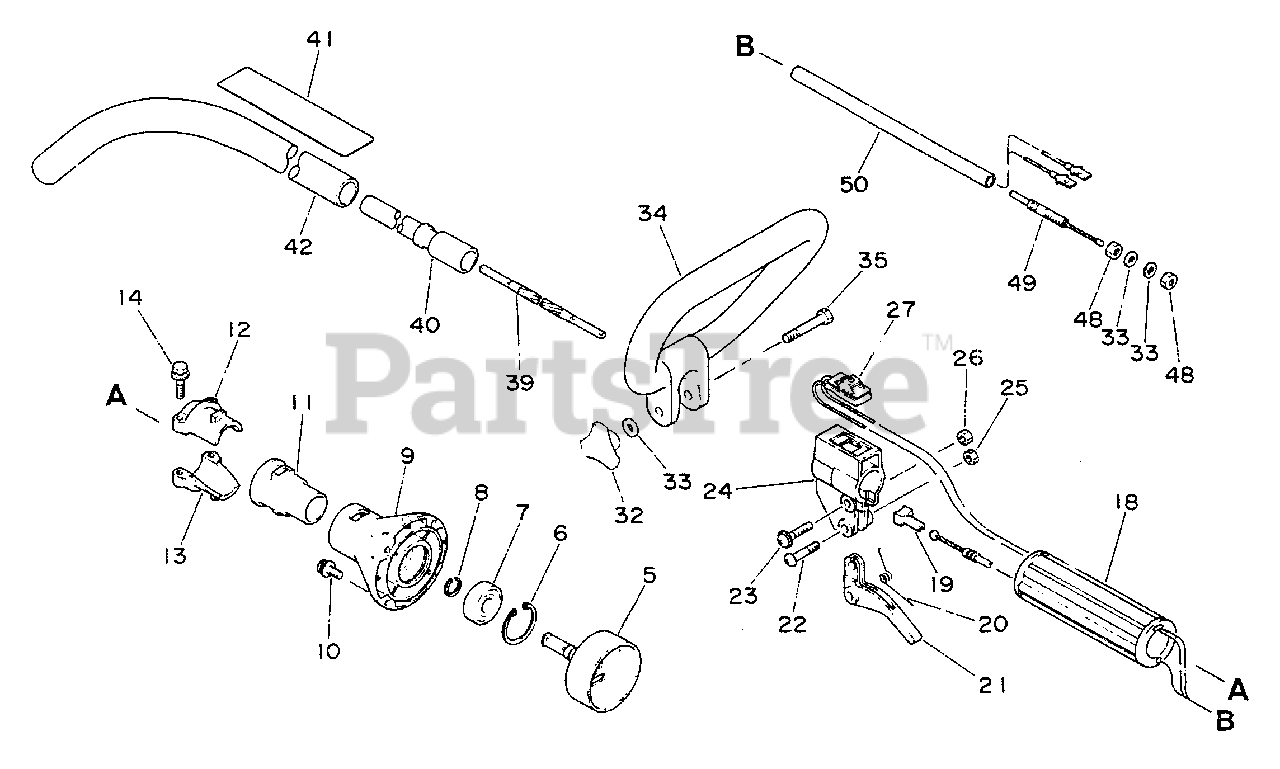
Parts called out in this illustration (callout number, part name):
5	DRUM, CLUTCH
6	RING, RETAINING - 32
7	BEARING, BALL - 6201
8	RING, RETAINING - 12
9	FLANGE, DRIVESHAFT
10	SCREW - 5X16
11	CUSHION
12	CLAMP, MAIN PIPE
13	Holder, housing
14	BOLT - 5X25
18	GRIP, HANDLE
19	GUIDE, CABLE
20	SPRING, TRIGGER
21	TRIGGER, THROTTLE
22	SCREW - 5X30
23	SCREW - 5X28
24	BRACKET, THROTTLE
25	LOCKNUT - 5
27	IGNITION SWITCH ASSY
32	KNOB, FASTENER
33	WASHER - 6
34	HANDLE
35	BOLT - 6X45
39	DRIVESHAFT - FLEXIBLE
40	BUSHING
41	LABEL - CAUTION
42	PIPE, MAIN
49	CABLE, THROTTLE
50	TUBE - VINYL
